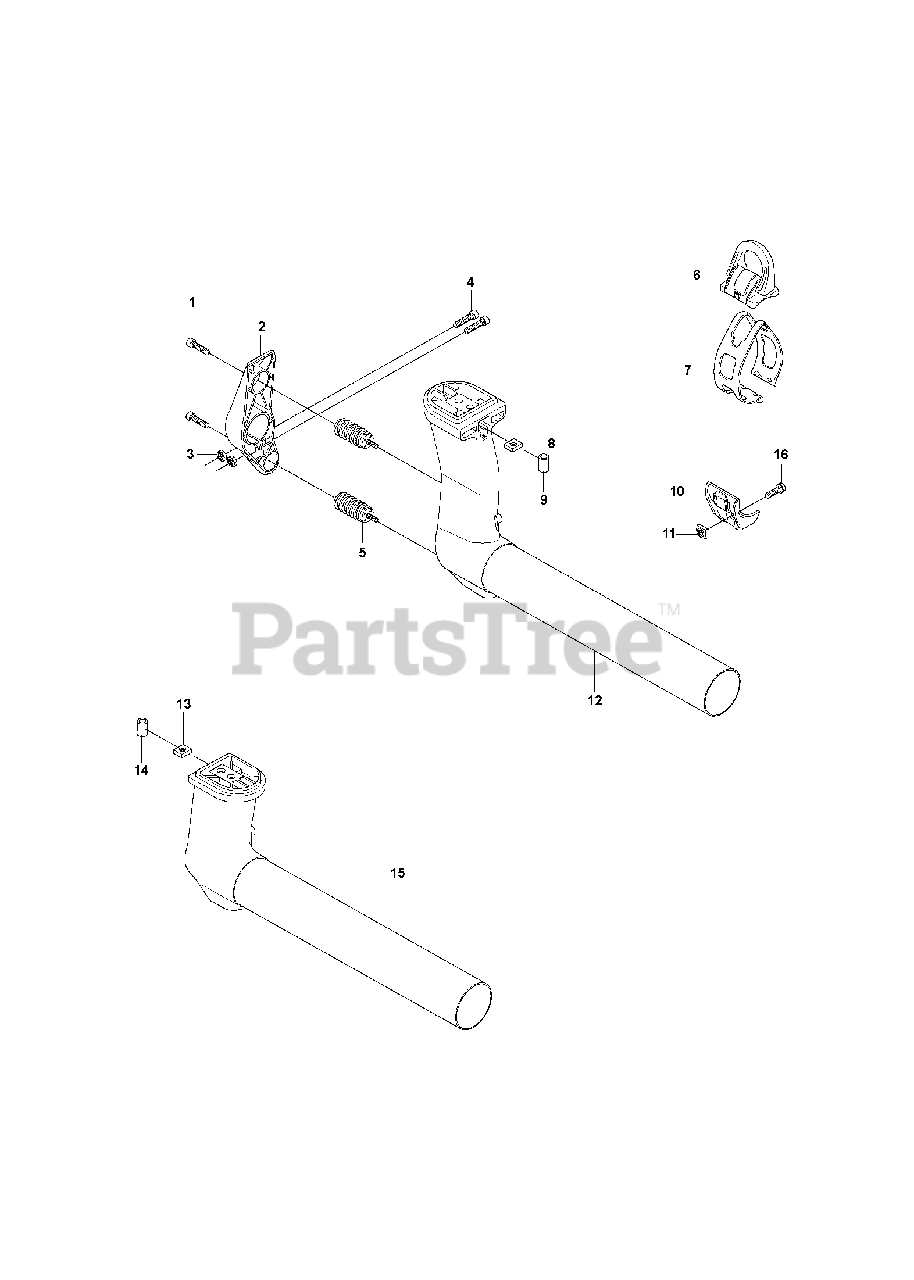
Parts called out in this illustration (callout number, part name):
6	HARNESS HANGER LOOP
10	BRACKET, LOWER HANGER
11	SQUARE NUT M5
